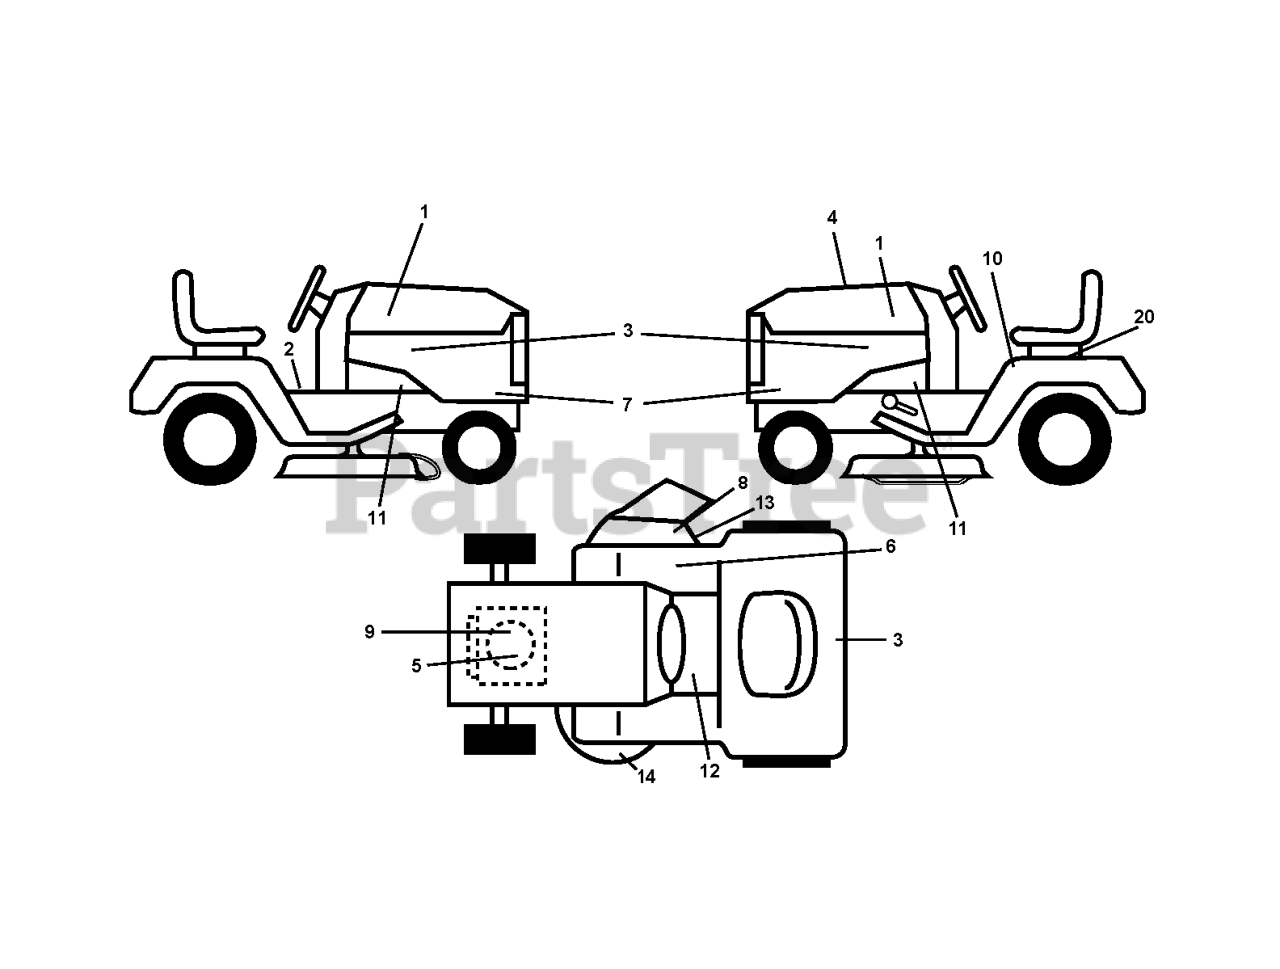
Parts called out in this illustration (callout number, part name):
2	DECAL PARK BRAKE
3	DECAL.HOOD.NAMELOGO.HUSQ
5	DECAL
6	Decal, Fender 100 DB/CE
8	DECAL.INTERNATIONL.CUTFINGER
10	LABEL
12	DECAL
13	DECAL, DEFLECT WARNING
14	DECAL.V-BELT.SCHEMATIC.36/38/9
20	DECAL BTRY SYMBOLS
